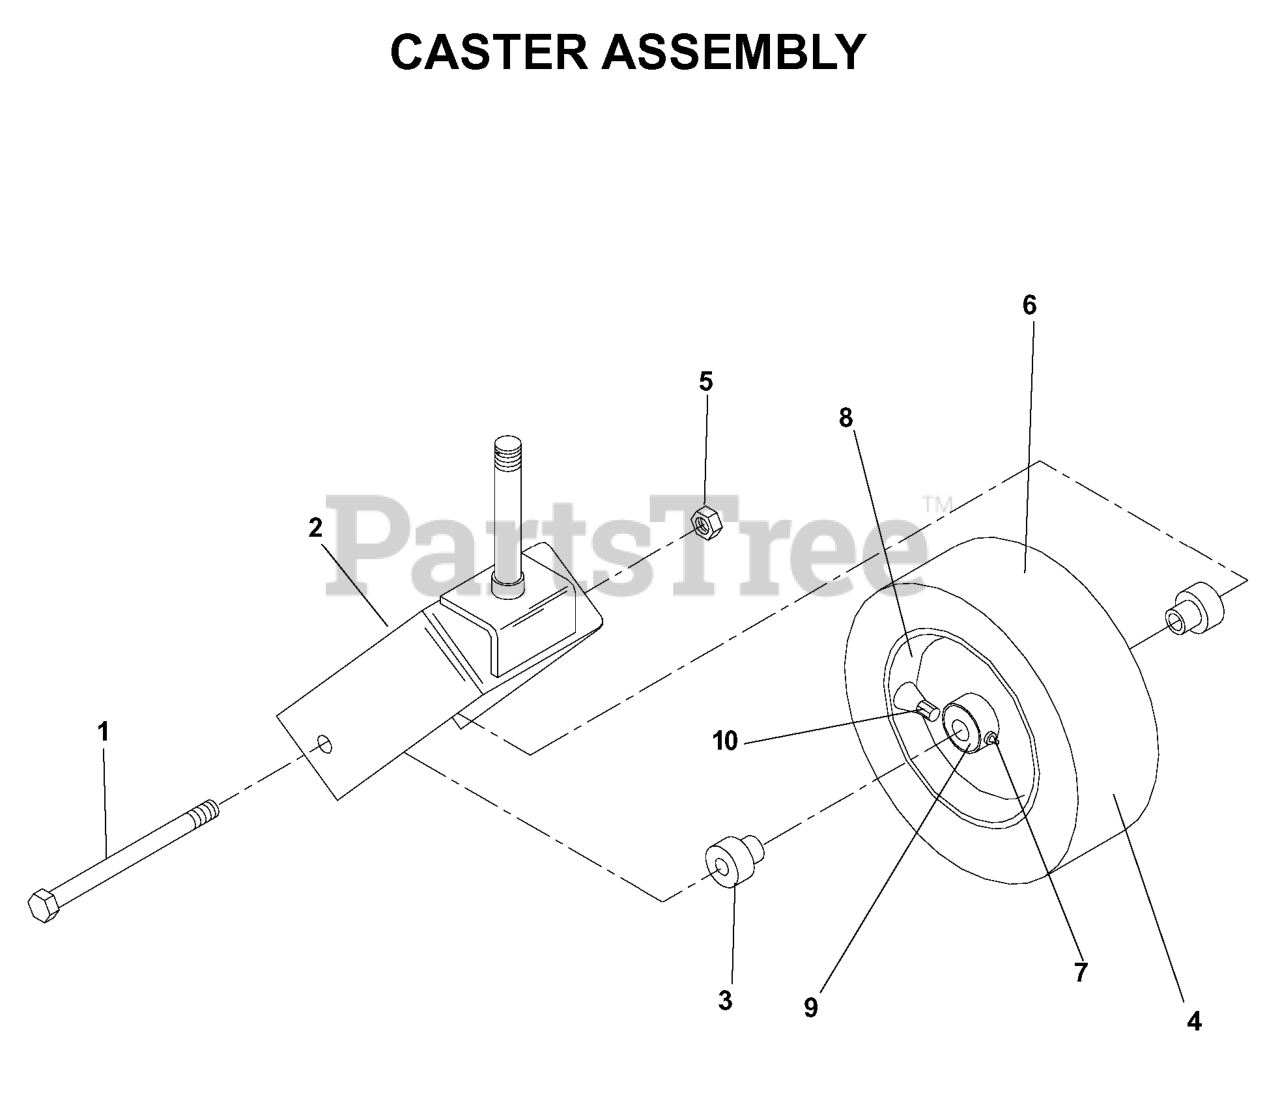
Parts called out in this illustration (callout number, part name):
1	HEX SCREW 1/2-13 X 9.5 GR5
2	CASTOR YOKE ORANGE
3	AXLE SPACER
4	FRONT TIRE ASSY
5	NUT 1/2-13 HEX NYLOC ZD
6	TIRE - SMOOTH 13X6.50-6
7	ZERK
10	VALVE STEM TR-412
539105525	TAPERED BEARING W/RACE
